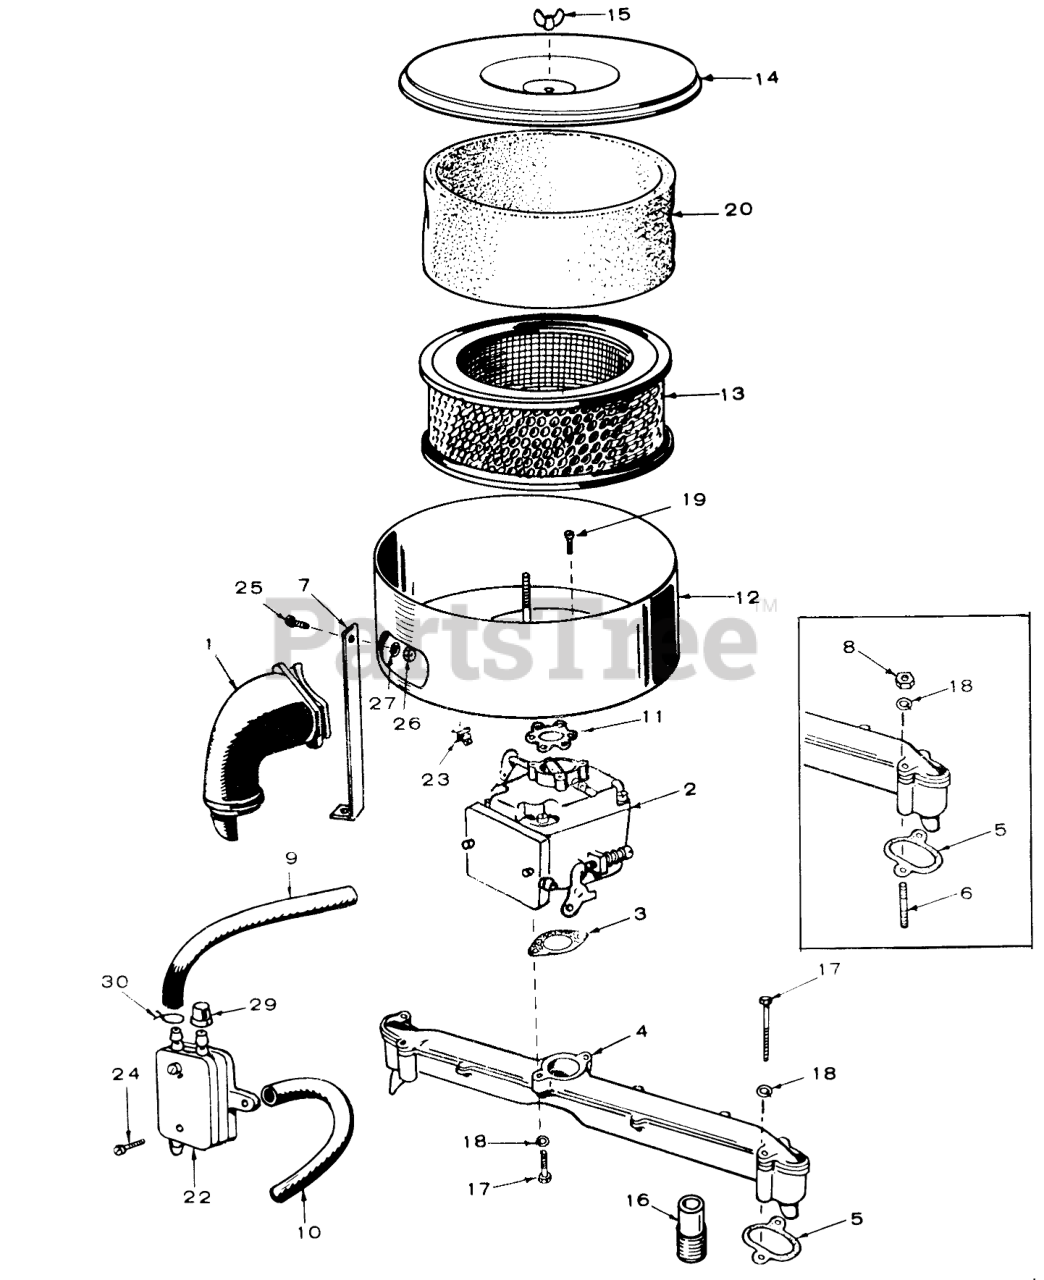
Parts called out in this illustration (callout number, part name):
1	Box Assembly, Breaker, (Includes Parts Marked )
1	Air Intake Tube
2	Gasket-Breaker Box Cover
2	Carburetor
3	Coil Mounting Clamp
3	Carburetor Mounting Gasket
4	SET-BREAKER POINT
4	Intake Manifold
5	Gasket, Intake
6	CONDENSER-BRKER PTS
6	Stud-Intake Manifold
7	Clip,Spark Plug Cable
7	Air Cleaner Support
8	Gasket,Breaker Box Mounting
8	Nut-Intake Manifold
9	Breaker Box Cover
9	Hose-Fuel Pump To Carburetor
10	Plunger
10	Hose-Fuel Pump Vacuum
11	Cable, Spark Plug (19")
11	Gasket, Air Cleaner Mounting
12	Ignition Coil
12	Air Cleaner Housing
13	Spark Plug Cable 16 3/4 in
13	ELEMENT-AIR CLEANER
14	Pan HD Screw 8-32 X 5/16
14	COVER-AIR CLEANER
15	Spark Plug
15	Wing Nut-Air Cleaner Cover
16	Wire Assy-Points To Coil
16	Nipple, (1" x 2 1/2")-Exhaust
17	SCREW, HEX CAP
17	Hex Bolt 1/4-20 X 3/4 in
18	WASHER, LOCK
19	SCREW, PAN HEAD
19	SCREW-RD HD10-32X3/8
20	Nut-Breaker Points
20	WRAPPER-AIR CLEAN EL
22	Fuel Pump
23	CLIP-BRKT CHOKE CAB
24	Sheet Metal Screw-Fuel Pump
25	Hex Bolt 1/4-20 X 1/2
26	Hex Nut 1/4-20
27	Lockwasher
29	Fuel Pump Cap
30	Clamp, Hose (7/16")
